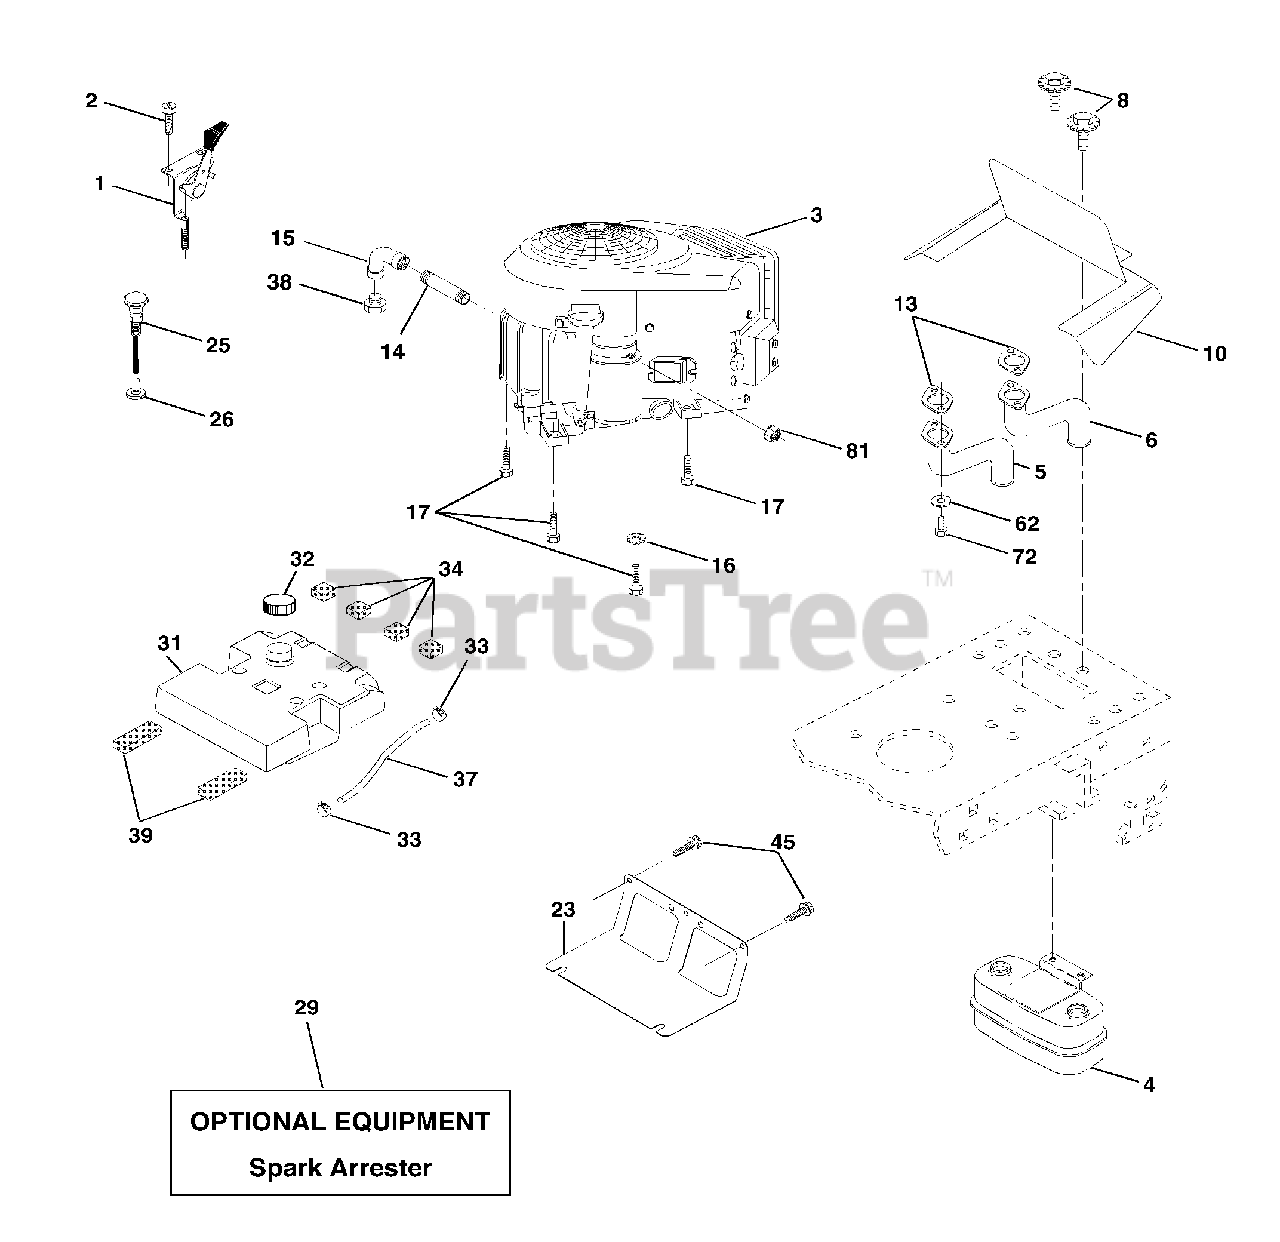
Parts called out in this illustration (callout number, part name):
1	Control Throttle
2	Screw Hw Hd Hi-Lo #13-16 x 3/4
4	Muffler Asm Twin Lo-Tone
5	Pipe Exhaust LH Intek
6	Pipe Exhaust RH Intek
8	Bolt 5/16-18 UNC x 3/4 w/Sems
10	Shield Browning Intek II
13	Muffler Gasket
14	Nipple Pipe 3/8 NPT x 4-1/2"
15	Elbow STD 90 Degree 3/8-18 NPT
16	Washer Lock Ext Tooth 3/8
17	Screw Thdrol 3/8-16 x 1-1/2
23	Shield Heat
25	Choke Control
26	Nut, Keps 3/8-24 UNF
29	Kit Spark Arrestor (Flat Scrn)
31	Tank Fuel 3 50 Rear
32	Cap Asm Fuel W/sym Vented
33	Clamp Hose Black
34	Pad, Spacer
37	Line Fuel
38	Plug Drain Oil
39	Pad, Idler
45	Screw Hexwsh Thdr 3/8-16 x 3/4
62	Washer Lock 5/16
72	Screw Hex Hd Cap 5/16-18 x 3/4
81	Nut Keps Hex 1/4-20 UNC
